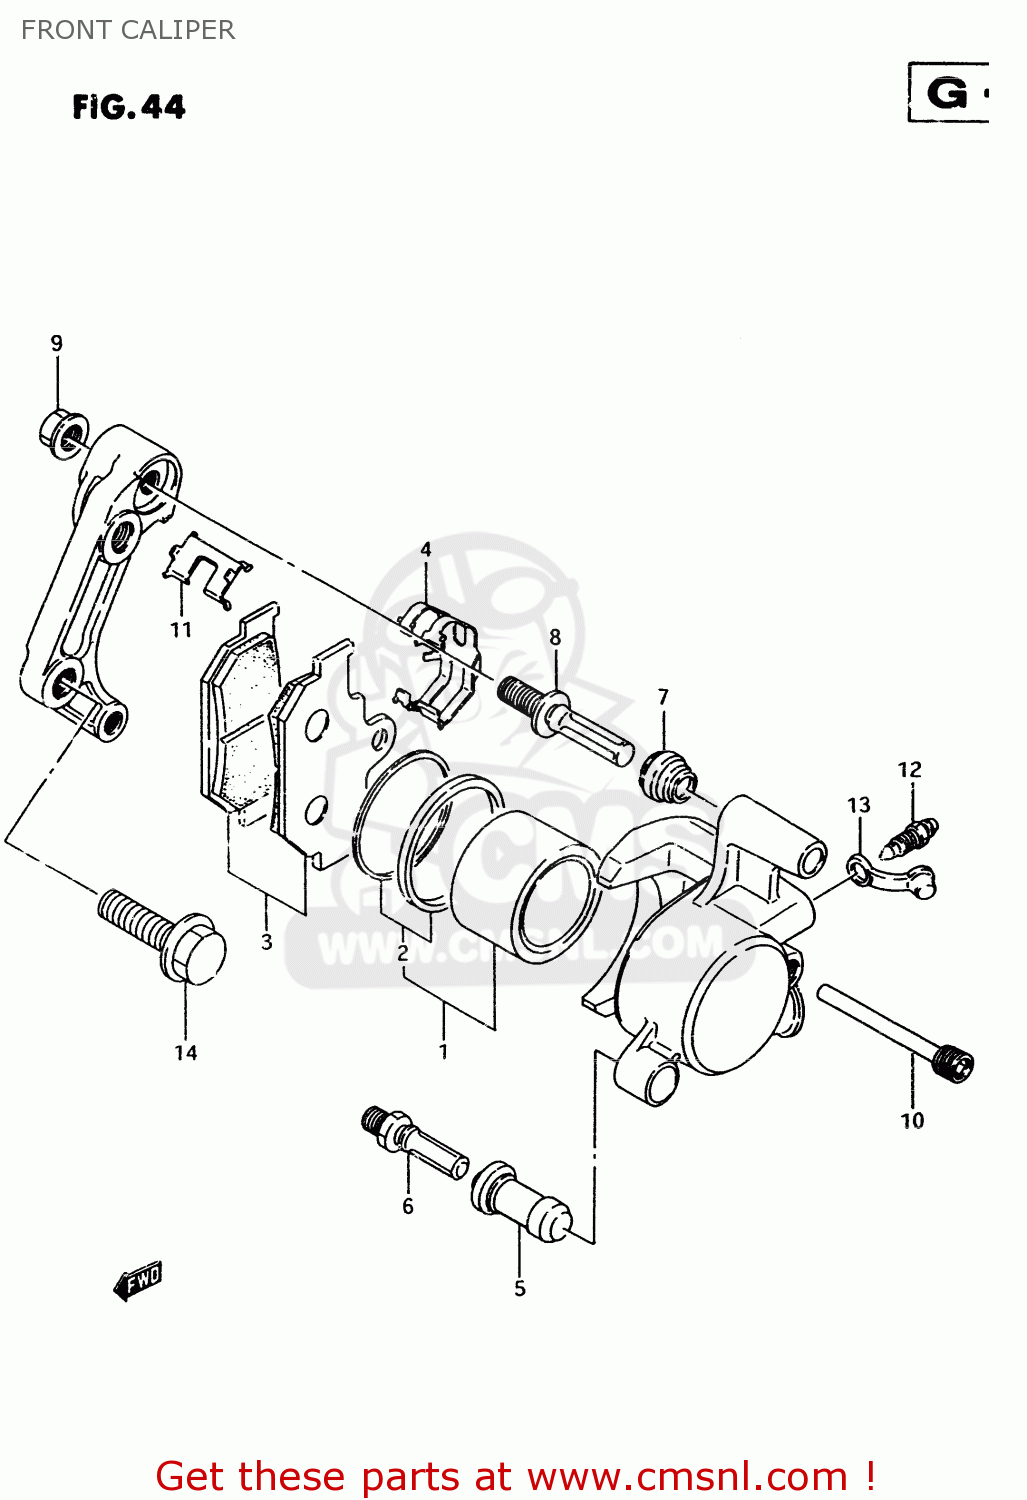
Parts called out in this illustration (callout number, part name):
1	PISTON SET
2	SEAL SET,PISTON
3	PAD SET (NAS)
4	SPRING
5	BOOT
6	PIN,BOLT
7	BOOT
8	PIN,SLIDE
9	NUT,SLIDE PIN
10	PIN,HANGER
11	RETAINER
12	BLEEDER
13	CAP,BLEEDER
14	BOLT
